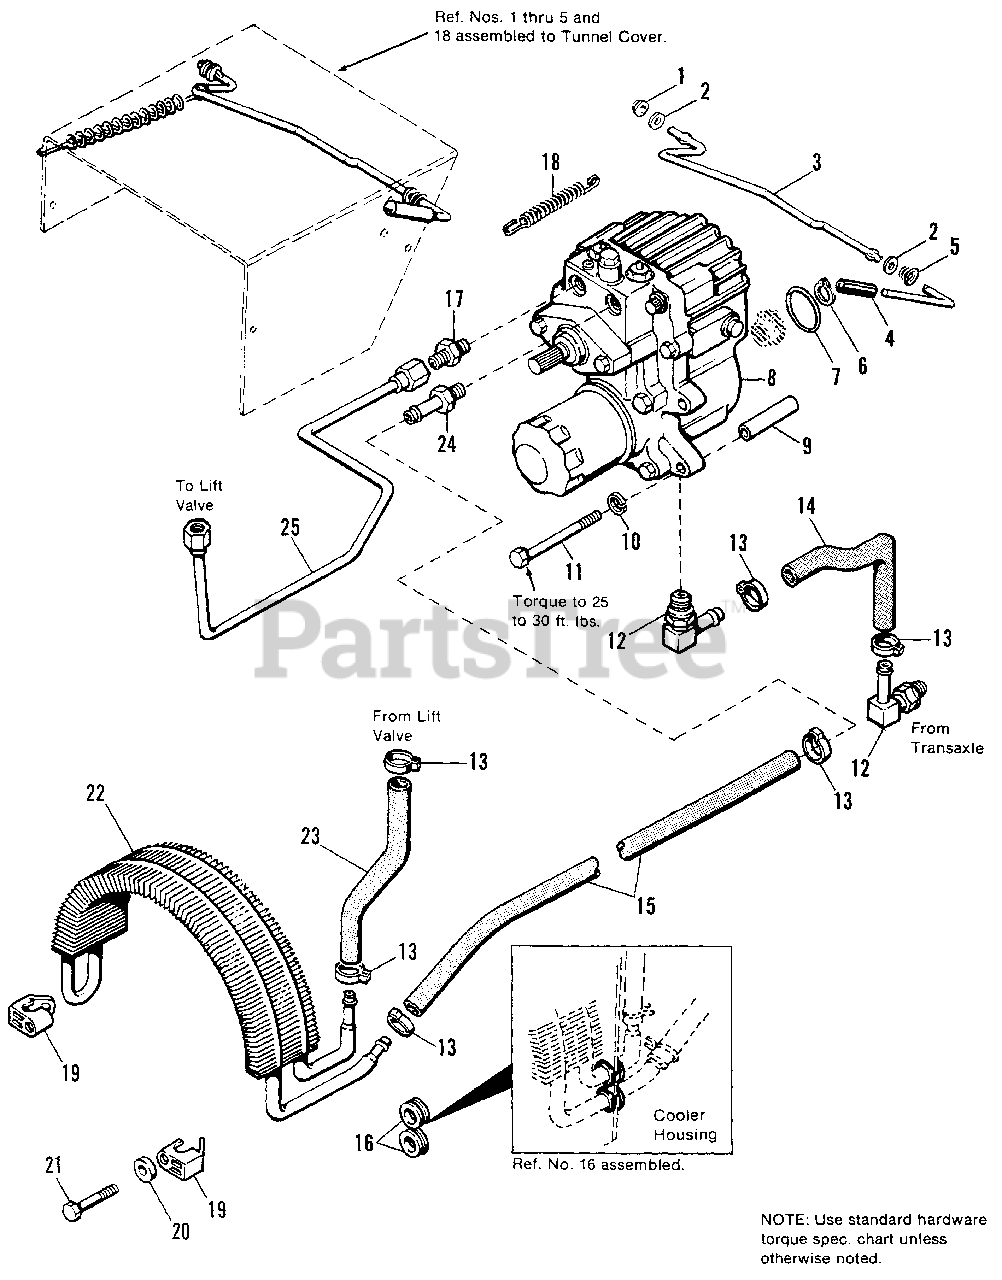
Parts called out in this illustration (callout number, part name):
1	PUSH NUT, 1/4
2	WASHER, 17/64 x 5/8 x 3/64
3	ROD, Hydrostatic Release
4	GRIP, Release Handle
6	RING, Retaining Ext. (.688 Shaft I.D., Early Models)
6	RING, Retaining Ext. (.625 Shaft I.D., Later Models)
8	HYDROSTATIC PUMP (See page 44 for parts breakdown.)
9	SPACER, Mounting
10	LOCKWASHER, 3/8
11	CAPSCREW, Hex Hd., 3/8-16 x 4
12	FITTING HYD., 7/8-14 O.R. x 5/8 90
13	CLAMP, Hose
14	HOSE, HYD., 5/8 Preformed
15	HOSE, Hyd., Return (Cooler to Pump)
16	GROMMET, Rubber, 5/8" x 1-1/8" O.D.
17	FITTING, Hyd., 9/16-18 O.R. x 9/16-18
18	SPRING, Tension, Hydrostatic Release
19	CLAMP, Oil Cooler
21	SCREW, Plastite, 1/4 x 1-1/2
22	COOLER, Oil
23	HOSE, Return, (Lift Valve to Cooler)
24	FITTING, Hyd., 9/16-18 O.R. x 1/2
25	TUBE ASSY., Hyd. (Pump to Lift Valve)
